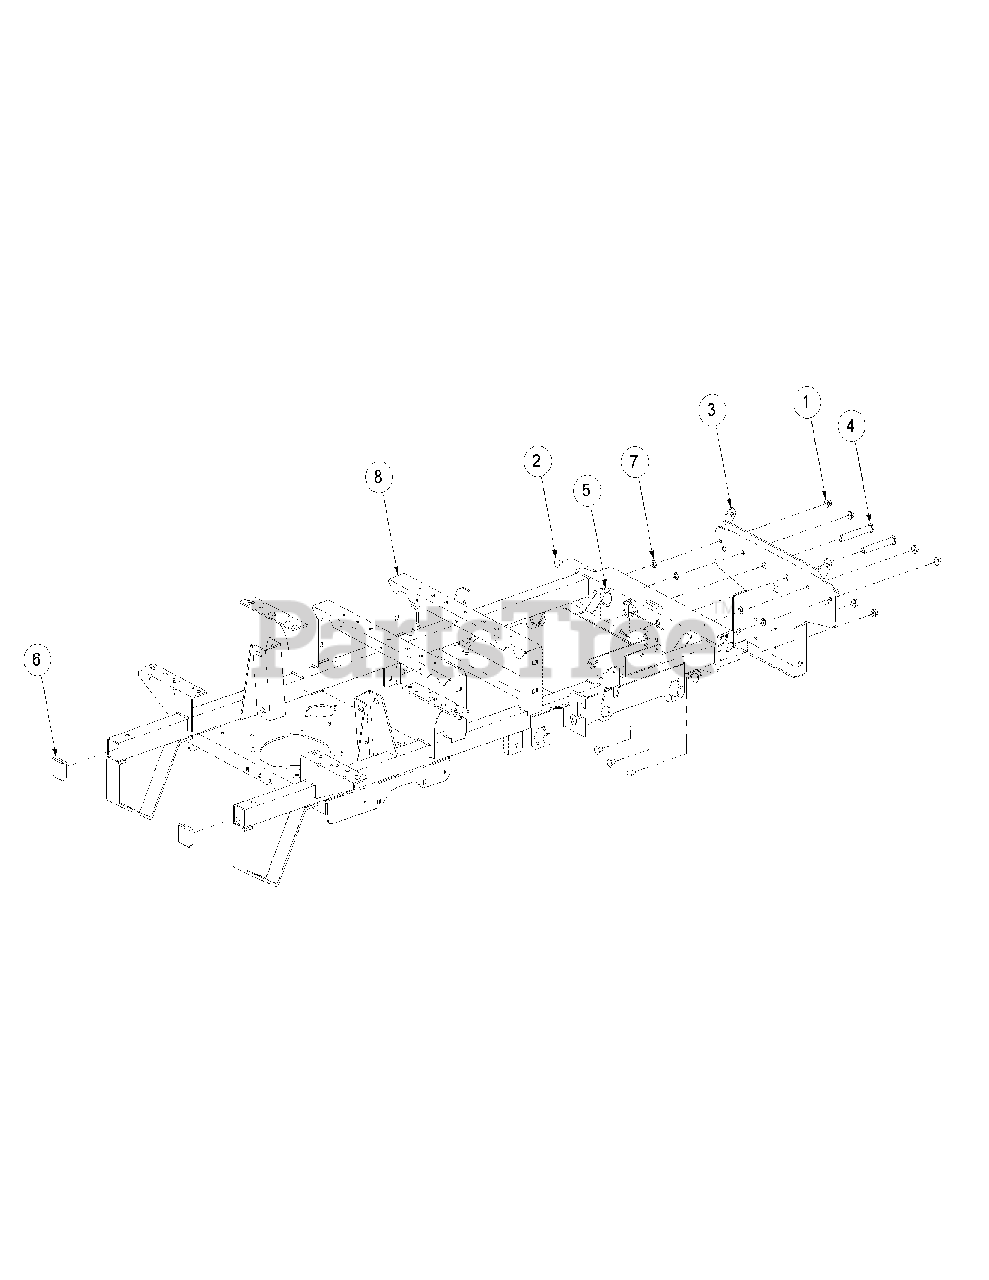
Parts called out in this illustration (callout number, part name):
1	Hex Nut, 3/8-16 Flange Lock
2	Carriage Bolt, 3/8-16 x .75 Long
3	Bracket Assembly, Frame, Front
4	Clevis Pin, .625 Dia x 4.375 Long
5	Linch Pin, 3/16 Dia.
6	Plug, Square Tube
7	Push Retainer, 3/8
8	Frame Assembly
